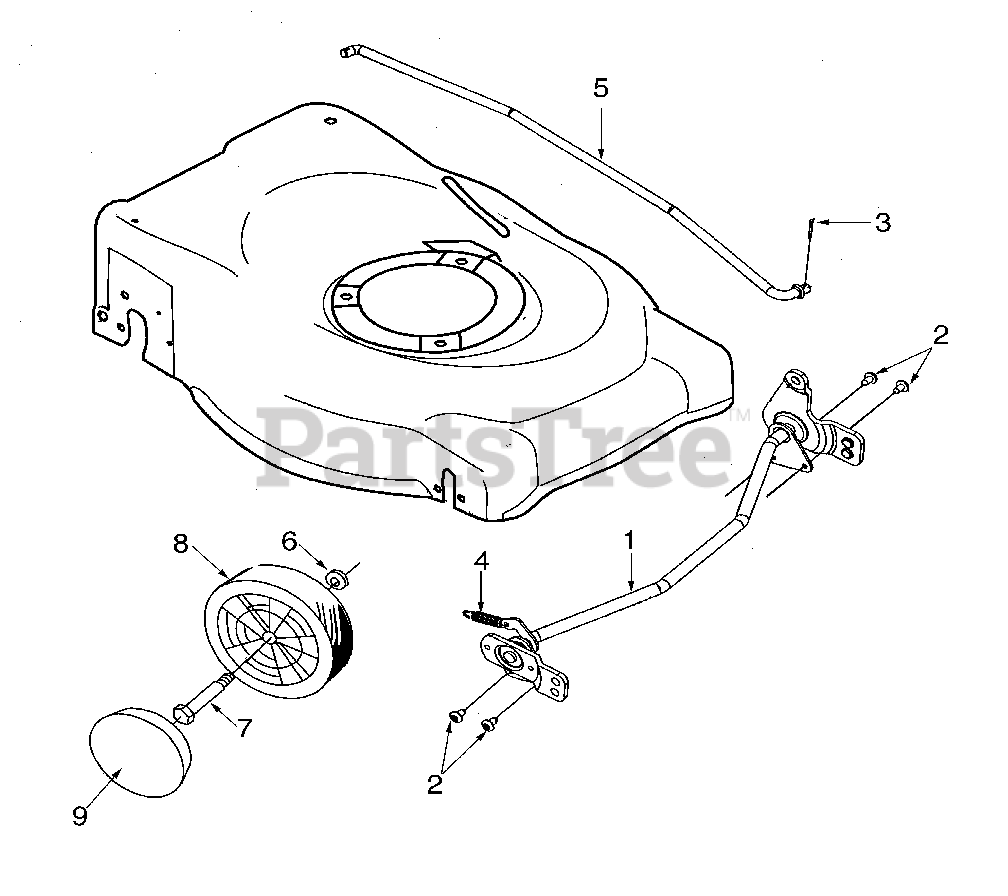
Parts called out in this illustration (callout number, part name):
2	AB Pan Scr. 1/4-14 x .50 Lg.
3	Cotter Pin .072 x 1.12 Lg.
4	Ext. Spring
5	Adj. Rod
6	Spr. Washer
7	Shl. Bolt .498 x 1.445 3/8-16
8	Wheel Ass'y - Complete
9	Hub Cap
